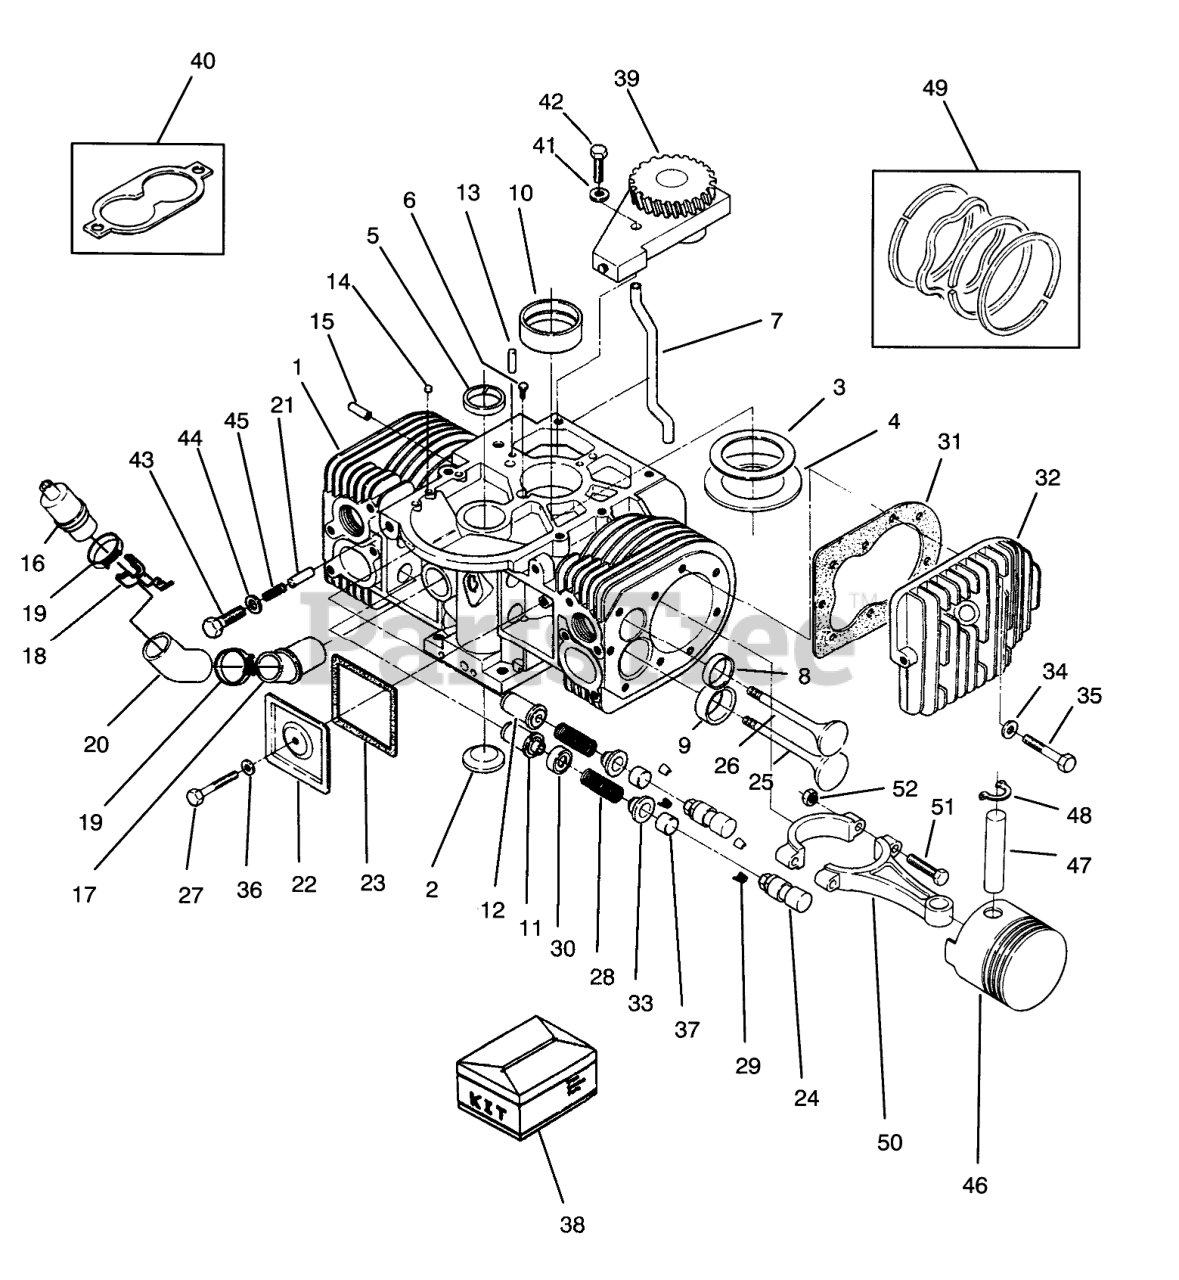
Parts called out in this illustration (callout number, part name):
1	CYLINDER BLOCK
2	Plug
3	PISTON
4	WASHER
5	SLEEVE-BEARING
6	Screw
7	OIL TUBE
8	Standard
9	SEAT-INT VALVE (STD)
10	Bearing-Up Crankshaft Std
11	Guide-Intake Valve
12	Guide-ExhaustValve
13	Pin
14	PLUG-CORE HOLE
15	TUBE-PORT, VACUUM
16	Breather Tube
17	BREATHER-ADAPTER
18	BREATHER-MTG BRKT
19	HOSE-CLAMP
20	BREATHER-HOSE
21	DOWEL-PIN PLUG
22	Cover-Valve
23	LOCK (SET OF 2)
24	TAPPET
25	Intake Valve
26	Exhaust Valve
27	HHCS 1/4-20 X 1 3/4
28	Spring
29	VALVE SPRING LOCK
30	Seal
31	GASKET
32	Side-Left
33	Washer
34	WASHER
35	Bolt
36	WASHER
37	Cap-Valve
38	ENGINE GASKET KIT
39	Pump-Oil
40	Kit-Oil Pump Gasket
41	Washer
42	Bolt
43	SCREW-HH
44	WASHER
45	SPRING
46	Standard
47	Pin-Piston
48	Piston Pin
49	RING/PISTON KIT
50	CONNECTING ROD W/NUT
